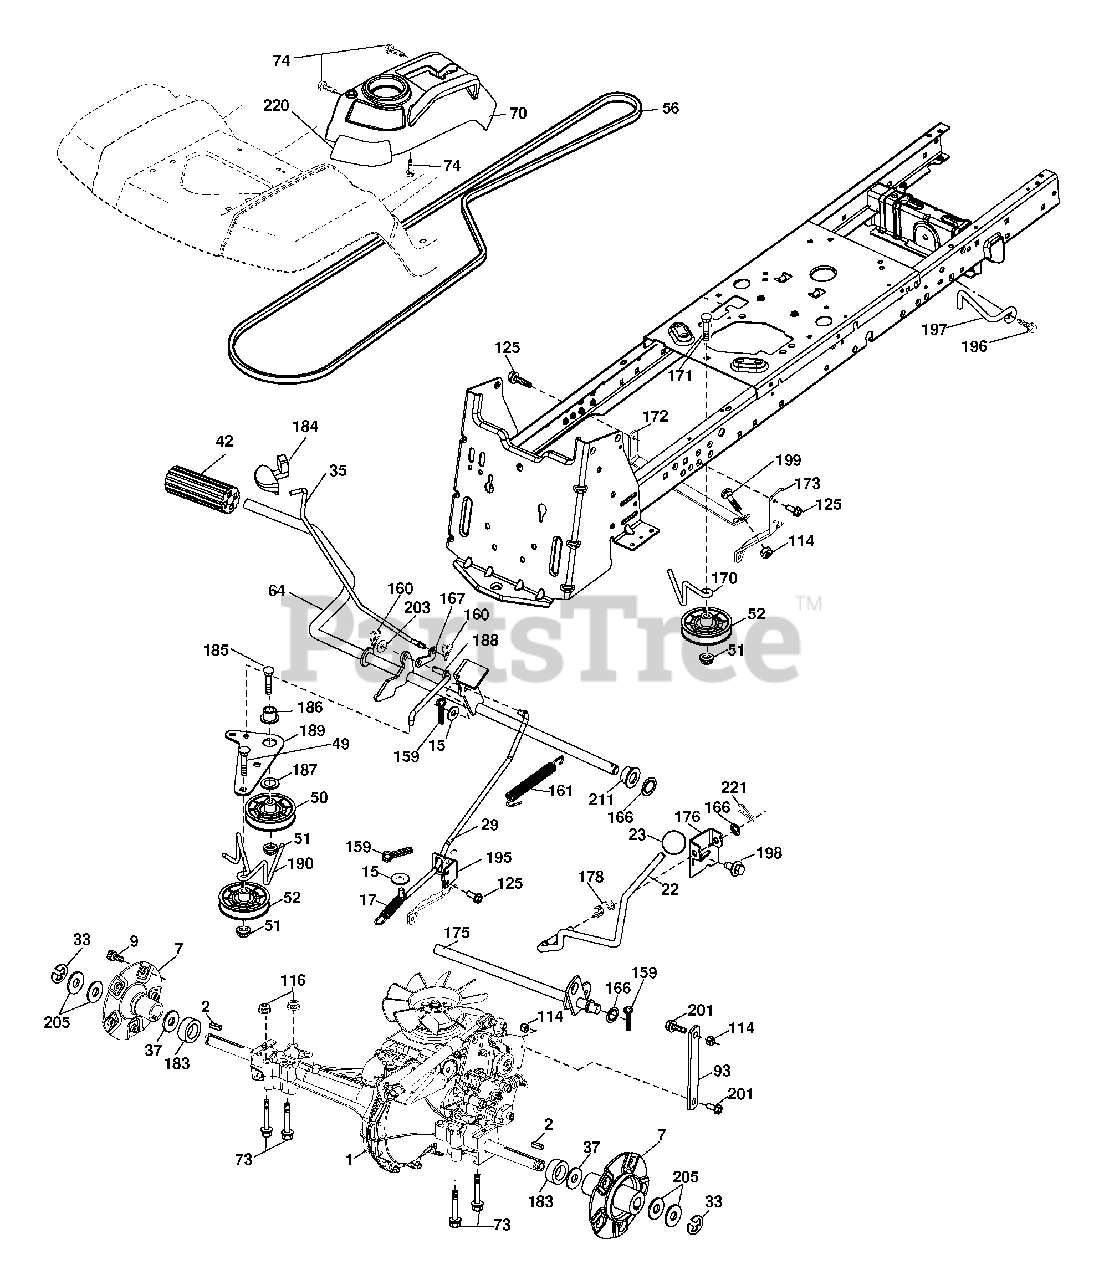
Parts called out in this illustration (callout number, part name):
2	Key 1/4 x 2.5
7	Hub Asm. Wheel
9	Bolt Hub Wheel
15	Washer 13/32 x 13/16 x 16 Ga.
17	Spring, Brake
22	Shifter Rod
29	Rod, Brake
35	Rod, Brake, Park
42	Cover, Foot Pedal
50	Pulley Idler Flat
51	Lock Nut 3/8-16
52	Idler V-Groove 910" Offset
56	V-Belt, Drive
64	Shaft Asm. Pedal Brake Control
70	Control Asm.
73	Bolt Hex Flghd 5/16-18 Gr. 5
74	Screw 1/4 x 1/2
93	Link Shift
114	Nut Lock Hex w/Insert 5/16-18 unc
116	Nut Lock Hex Flange 5/16-18
125	Screw 5/16-18 x 3/4
159	Pin Cotter 1/8 x 3/4
160	Retainer Clip
161	Spring, Return, Clutch
166	Nut Push .625
167	Latch Brake Parking
170	Keeper Belt Centerspan
172	Strap Torque LH
173	Strap Torque RH
175	Shaft Asm Shift
176	Arm, Shift Rod
178	Spring Shift
183	Spacer Split
184	Handle Parking Brake
185	Bolt Rdhd Sqnk 3/8-16 x 2-1/2
186	Spacer Retainer
187	Washer
188	Link Clutch Ground Drive
189	Bellcrank Ground Drive
190	Keeper Bellcrank Ground Dr.
195	Bracket Rod Brake
196	Screw 3/8-16 x 1
197	Bracket Clutch Anti-Rotation
198	Screw 7/16-14 x 7/8 Flghd
199	Bolt Rdhd Sqnk 5/16-18 unc x 1
201	Bolt Shoulder 5/16-18 unc
203	Washer 11/32 x 11/16 x 16 Ga.
220	Reflector RH
221	Retainer Spring Clip Handle
